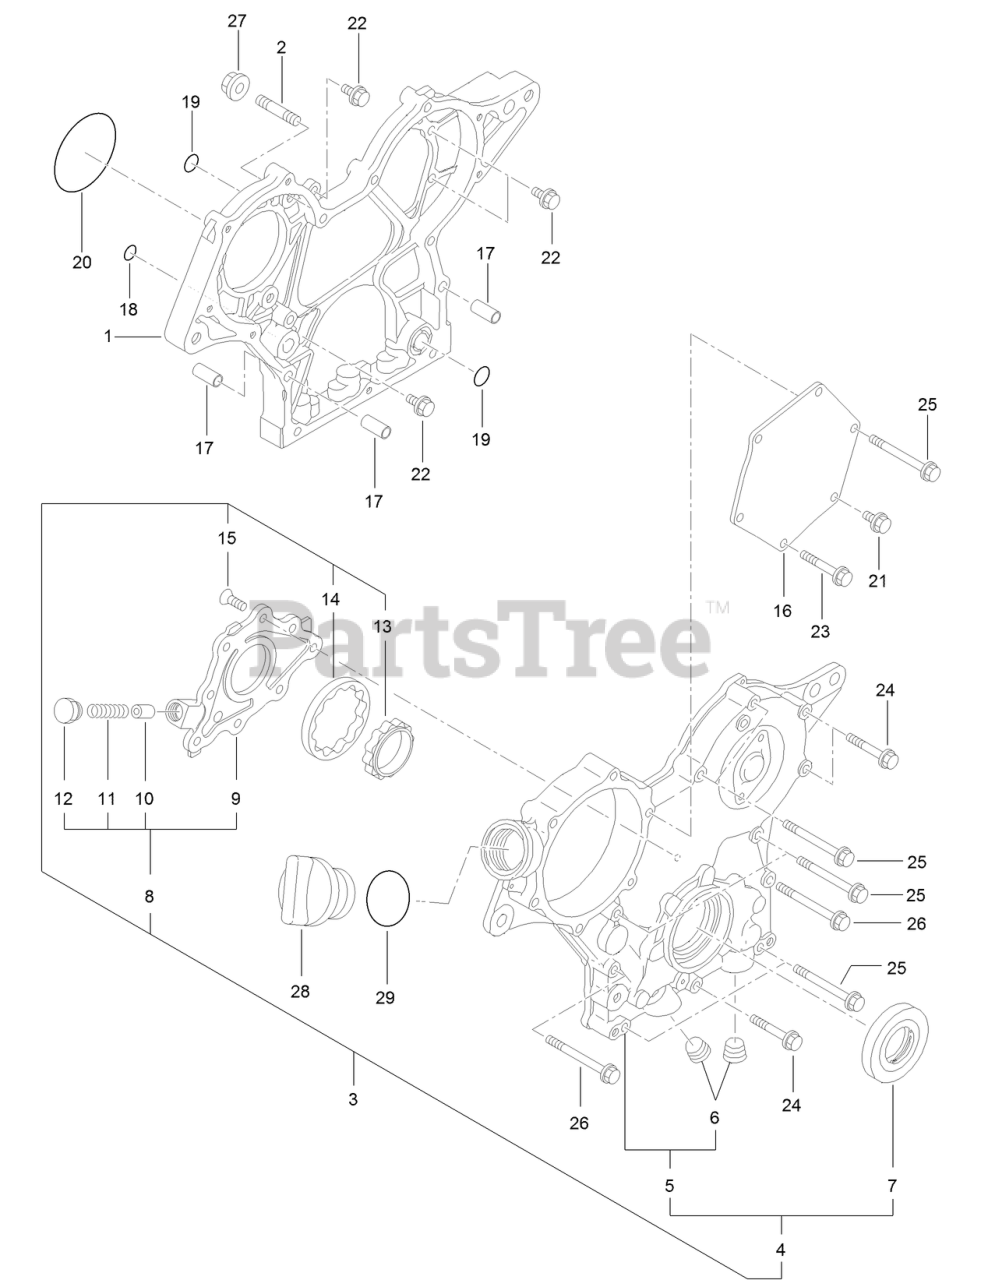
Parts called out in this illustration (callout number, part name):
1	CASE-GEAR
2	BOLT-STUD
3	COVER ASM-GEAR CASE
4	COVER ASSY-GEAR CASE
5	COVER-GEAR CASE
7	SEAL-OIL
8	COVER ASM
9	COVER-PUMP
10	VALVE-RELIEF
11	SPRING
13	ROTOR-INNER
14	ROTOR-OUTER
16	COVER-PUMP
17	PIPE-DOWEL
18	O-RING
19	O-RING
20	O-RING
28	COVER-FILLER
29	O-RING
